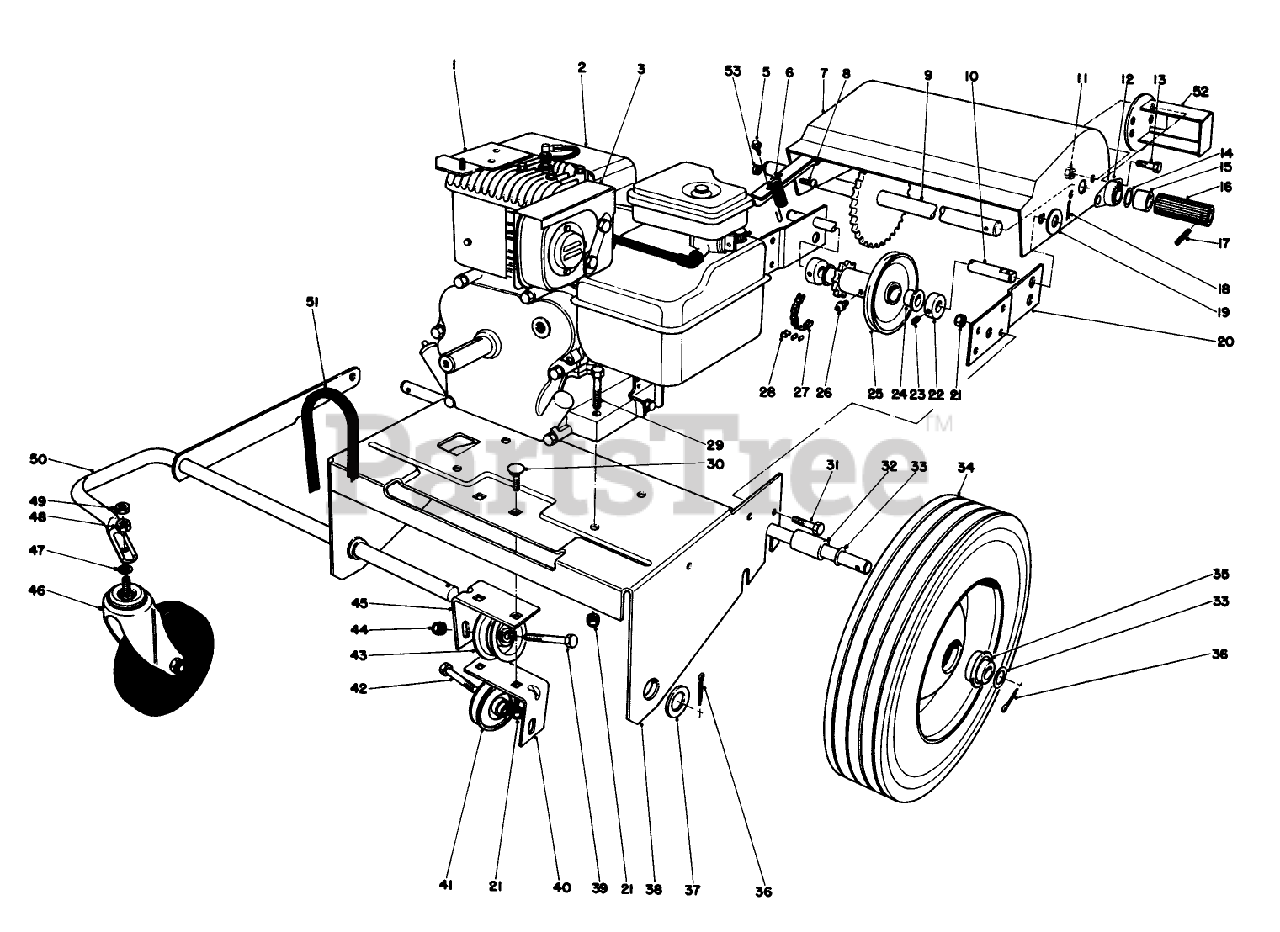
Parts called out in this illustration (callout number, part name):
1	MTG BRKT WA B
2	Engine
3	HEAT SHIELD
5	SCREW-HH
6	SPRING-TRACTION
7	GUARD WA
8	10-24 X 3/8 PAN HD SC
9	SHAFT-WHEEL, FRICTION
10	SHAFT-IDLER
11	NUT-LOCK, NI
12	BEARING-MOUNT, FLANGE
13	SCREW-HH
14	WASHER
15	SPACER
16	WHEEL-FRICTION
17	PIN-ROLL, SLOTTED
18	PIN-COTTER
19	WASHER-FLAT
20	Bracket Mounting
21	NUT-LOCK, CONE
22	Set Screw Collar (Incl. Ref. #23)
23	SCREW-SET, HSH
24	BUSHING-FLANGE
25	Idler Assembly (Incl. Ref. #24 & 26)
26	FITTING-GREASE
27	Traction Chain (Incl. Ref. #28)
28	Connecting Link
29	SCREW-HH
30	SCREW-CARR
31	Screw
32	SPACER-AXLE
33	WASHER
34	Wheel (Incl. Ref.#35)
35	BEARING
36	PIN-COTTER
37	WASHER-FLAT
38	Engine Plate
39	SCREW-HH
40	Bracket-Idler Mount L.H.
41	PULLEY-IDLER
42	SCREW-HH
43	PULLEY-IDLER
44	NUT-LOCK, CONE
45	Bracket-Idler Mount R.H.
46	CASTER
47	WASHER-LOCK/INT
48	NUT-HH
49	1/2-13 CONELOCK NUT
50	Front Wheel Support
51	BELT-V
52	Guard
53	NUT-KEPS
